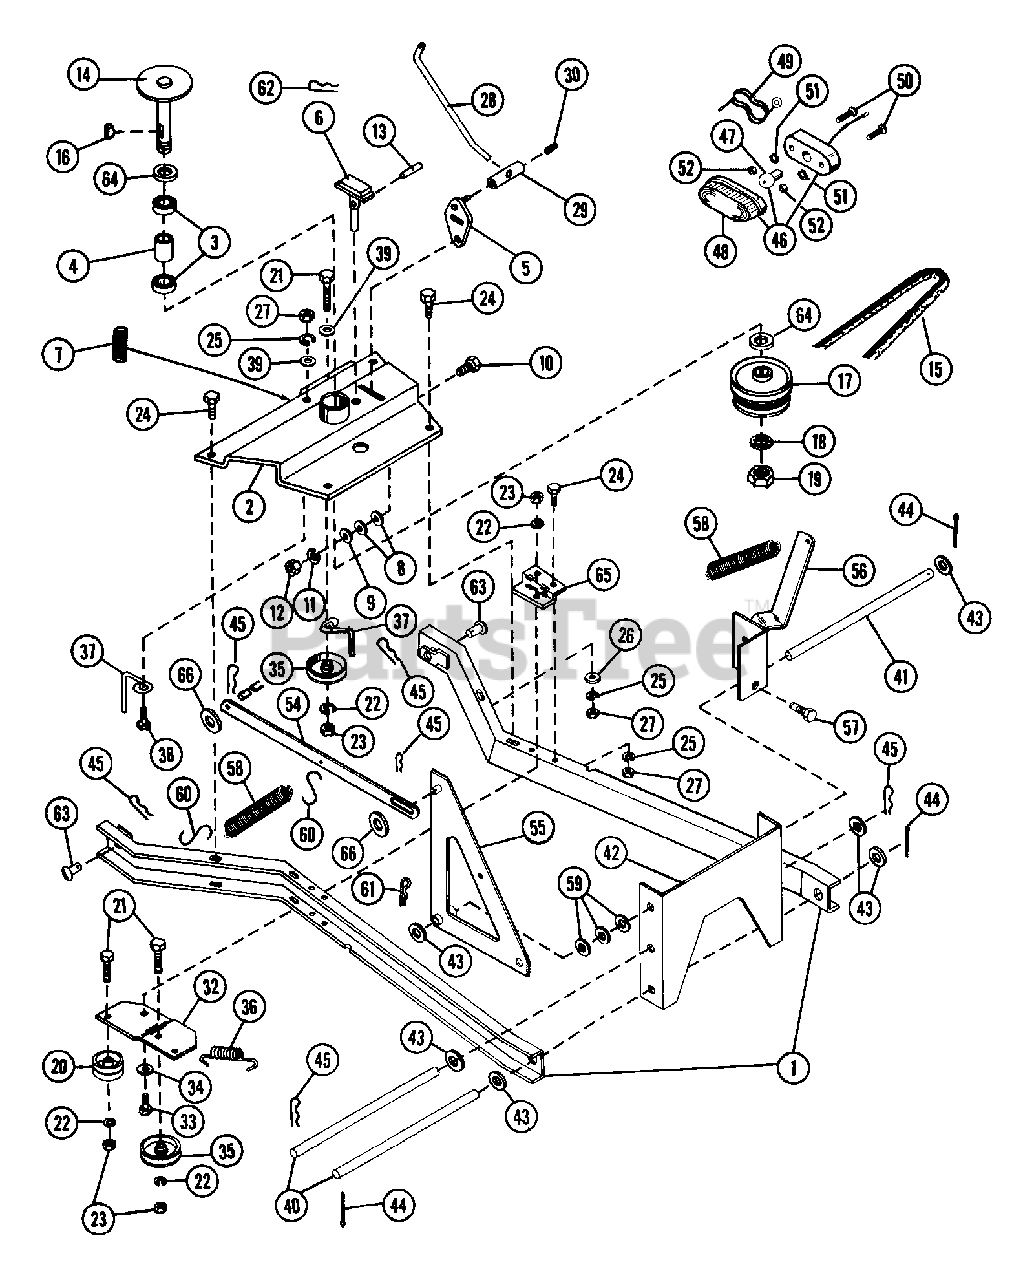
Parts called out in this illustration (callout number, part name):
1	CHANNEL
2	SPINDLE HOUSING
3	BRG-BALL .750X1.781X.61
4	SPACER .765X1.000X1.252
5	BRAKE ACTUATOR
6	BRAKE PLUNGER
7	SG-COMP ??X.44X?? WLD 10
8	WSHR-FL-STL .265X.500X.087 PL
9	WSHR-FL-STL.312X.734X.065PL
10	BLT-HEX .25-20X.75 PL GR5
11	WSHR-LK .250X.077 HVY PL
12	NUT-HEX .250-20 PL
13	PIN-ROLL .188X1.50
14	SPINDLE SHAFT
15	V-BELT, 4L-RAW EDGE
16	KEY-WDRF .188X.75X.313 SAE 9
17	DOUBLE SHEAVE
18	WSHR-LK-INT .750X.050 MED
19	NUT-JAM .75-10 PL
20	IDLER-FLAT 2.25 X .38
21	BLT-HEX .38-16X1.75 PL GR2
22	WSHR-LK .375X.115 HVY PL
23	NUT-HEX .375-16
24	BLT-HEX .31-18X.75 PL GR5
25	WSHR-LK .312X.097 PL HVY
26	WSHR-FL-STL .323X.625X.062 PL
27	NUT-HEX .312-18
28	BRAKE ROD
29	ROD ADAPTER
30	SCR-SET .32-18X.38 SKHCUPNL OH
31	IDLER MOUNT
32	IDLER ARM
33	SHOULDER BOLT .50 X .281
34	WSHR-FL-STL .511X1.441X.125 PL
35	IDLER-V 3.06 X .38
36	SG-TENS .080X.73X3.06 WLD 20
37	BELT FINGER
38	BLT-HEX .31-18X1.00 PL GR 2
39	WSHR-FL-STL .38X.875X.083 PL
40	PIVOT ROD
41	MOUNT ROD
42	PIVOT SUPPORT
43	WSHR-FL-STL.656X1.312X.095 PL
44	PIN-COTR .15X1.50
45	PIN-HAIR INT .09X.188 PL
46	TAIL LIGHT
47	INSTRUCTION SHEET, ZOOM BAGGER
48	TAIL LIGHT LENS
49	TAIL LIGHT WIRE
50	SCR-MCH 10-24X.50 SLTR PL
51	WSHR-LK 10X.047 MED PL
52	NUT-HEX 10-24 PL
53	CABLE RETAINER
54	LIFT STRAP
55	LIFT BELLCRANK
56	SPRING ANCHOR
57	BLT-HEX .50-13X1.25 PL GR2
58	SG-TENS .187X1.50X9.94 WLD 40
59	WSHR-FL-STL.656X1.312X.095 PL
61	PIN-HAIR INT .14X.4X2.75
62	PIN-HAIR INT .08X.18X1.18
63	PIN-CLEV .494X1.25 YWZC
64	WSHR-FL-STL .781X1.250X.059 PL
65	IDLER MOUNT
66	WSHR-FL-STL .531X1.062X.095 PL
